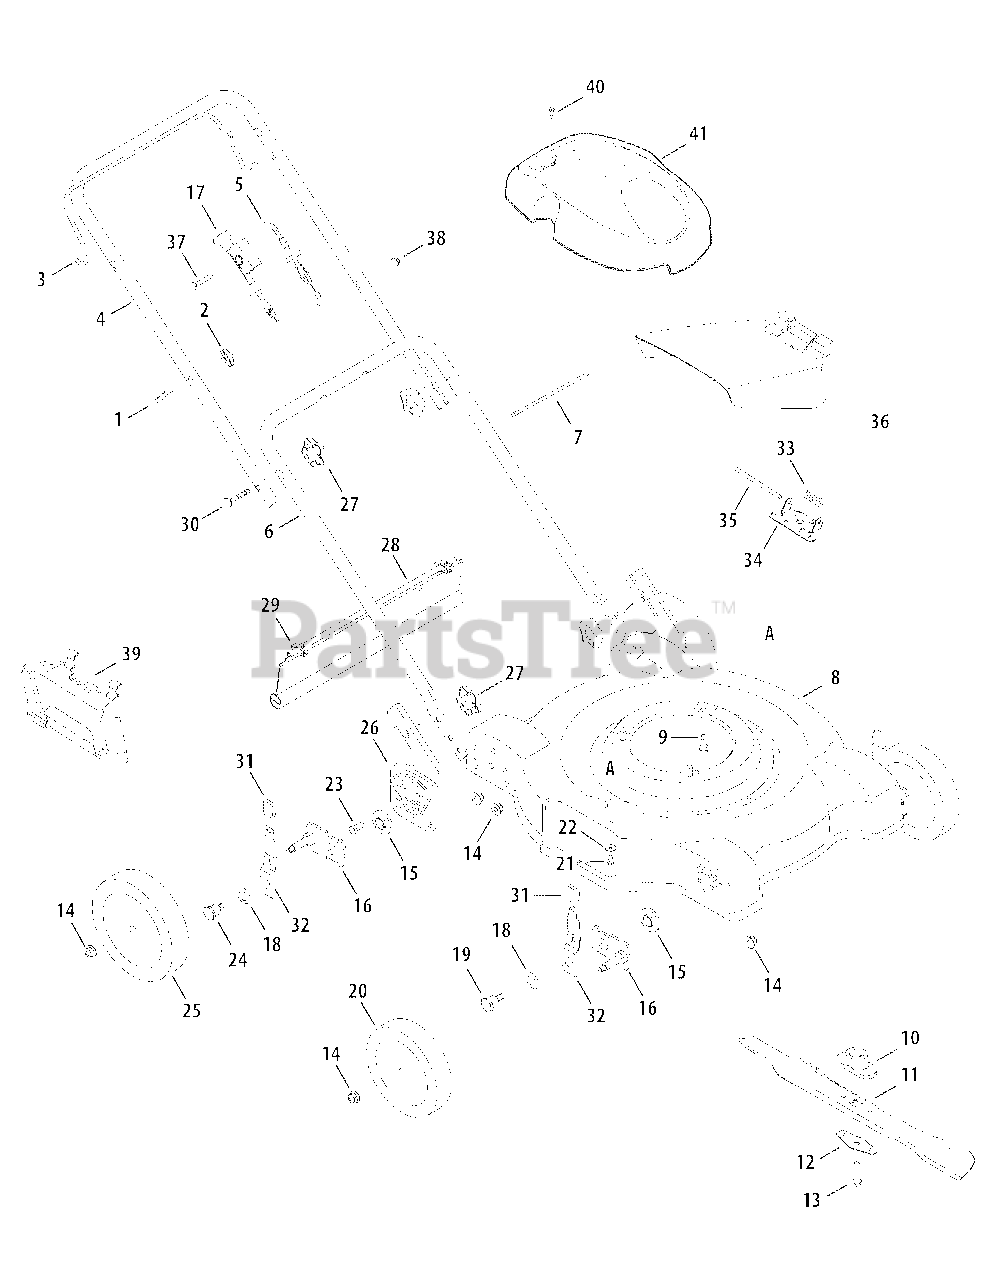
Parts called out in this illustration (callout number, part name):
1	Eye Bolt
2	Wing Nut
5	Control Cable
7	Cable Tie
9	TT Screw, 3/8-16 x 1.0
10	Blade Adapter
11	Standard Blade, 22"
11	Mulching Blade, 22"
12	Blade Bell Support
13	Screw, 3/8-24 x 1.5
14	Lock Nut, 3/8-16
15	Height Adjuster Bearing
16	Pivot Arm
17	Choke Cable
18	Bell Washer, .760 OD x 1.25 OD
19	Shoulder Screw
20	Front Wheel, 7 x 1.8, Bar
21	TT Screw, 1/4-20 x .5
22	Bell Washer, .265 ID x .75 OD
23	Screw, 3/8-16 x .75
24	Shoulder Screw
25	Rear Wheel, 8 x 1.8, Bar
27	Star Knob
28	Trailshield
29	Hinge Clip
30	Carriage Bolt, 5/16-18 x 2
31	Knob
32	Lever
33	Torsion Spring
34	Chute Hinge
35	Hinge Pin
36	Hinged Chute Deflector Assembly
37	Screw, 1/4-20 x 1.50
38	Nut, Flange Lock, 1/4-20
39	Mulching Baffle
40	Screw, Machine, M4-.7
41	Engine Shroud
